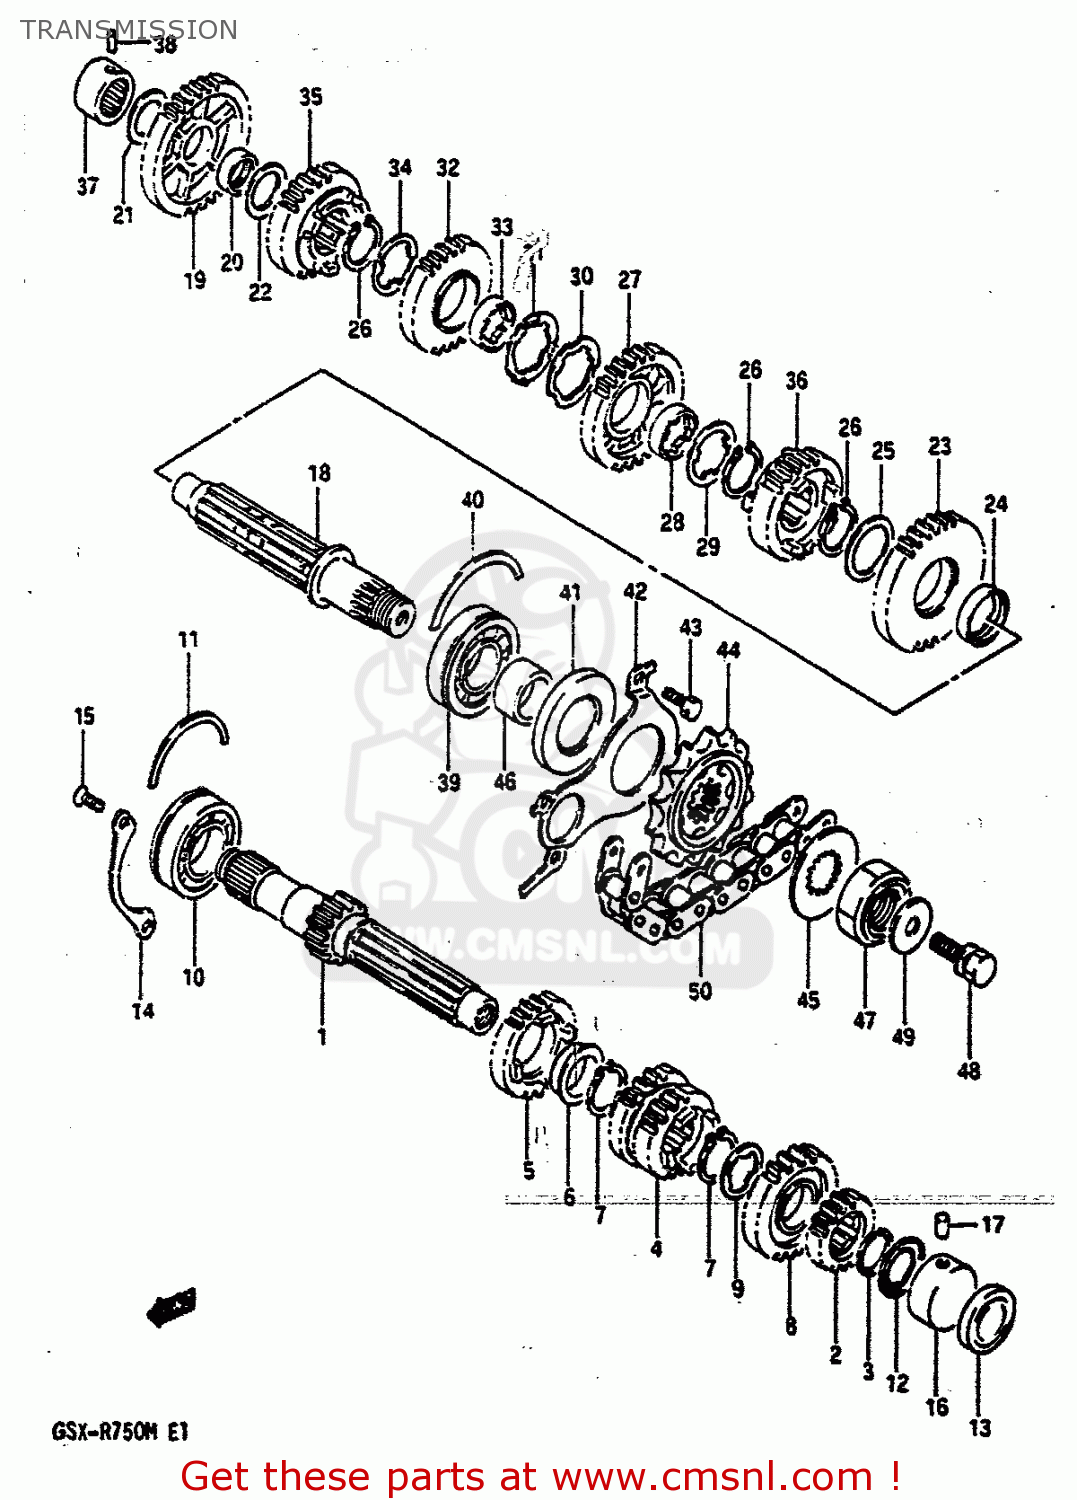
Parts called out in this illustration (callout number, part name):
1	SHAFT,COUNTER(NT:13)
2	GEAR,2ND DRIVE(NT:16)
3	CIRCLIP
4	GEAR,3RD & 4TH DRIVE(NT:17/20)
5	GEAR,5TH DRIVE(NT:22)
6	BUSHING
7	RING,SNAP
8	GEAR,SIXTH DRIVE (NT:21)
9	WASHER,LOCK
10	BEARING(25X62X17)
11	C-RING
12	SEAL,OIL(20X31.2X2.7)
13	CAP,COUNTER SHAFT,L
14	RETAINER,CNTR SHAFT BEARING
15	SCREW
16	BEARING(20X34X17.5)
17	PIN
18	SHAFT,DRIVE
19	GEAR,1ST DRIVEN(NT:36)
20	BUSH(22X26X9)
21	WASHER
22	WASHER
23	GEAR,2ND DRIVEN(NT:33)
24	BUSH(28X32X8)
25	WASHER, THRUST
26	CIRCLIP
27	GEAR,3RD DRIVEN
28	BUSH
29	WASHER,LOCK
30	WASHER,LOCK
31	WASHER
32	GEAR,4TH DRIVEN(NT:28)
33	BUSH
34	WASHER,LOCK
35	GEAR,5TH DRIVEN(NT:27)
36	GEAR,6TH DRIVEN
37	BEARING(20X34X20)
38	PIN
39	BEARING(25X62X17)
40	C-RING
41	SEAL,OIL(34X62X6)
42	RETAINER,DRIVE SHAFT OIL SEAL
43	BOLT
44	SPROCKET,ENGINE (NT:15)
45	WASHER,THRUST
46	SPACER,ENGINE SPROCKET
47	NUT
48	BOLT
49	WASHER
50	CHAIN ASSEMBLY,DRIVE 50GSV
